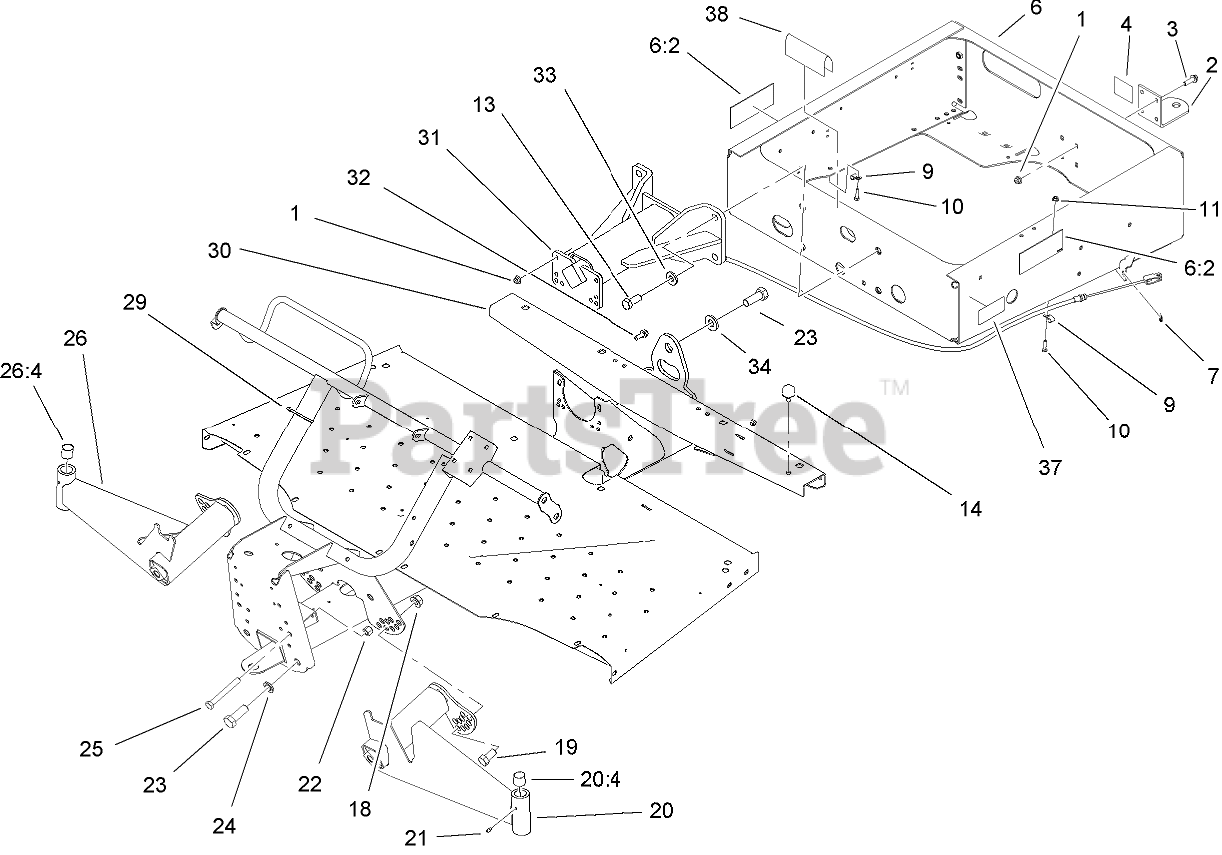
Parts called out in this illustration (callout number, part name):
1	NUT-HF, NI
2	HITCH-DUTY, LIGHT
3	SCREW-HHF
4	DECAL-RATING, HITCH (LIGHT DUTY)
6	REAR FRAME ASM
6:2	DECAL-WARNING
7	RING-RETAINING, EXTERNAL
9	CLAMP-R
10	SCREW-HH
11	NUT-HF
13	SCREW-HH
14	BUMPER-RUBBER
18	NUT-HF
19	SCREW-HH
20	LH A-ARM ASM
20:4	BUSHING
21	FITTING-GREASE
22	NUT-LOCK, NI
23	SCREW-HH
24	WASHER-LOCK, INT
25	SCREW-HH
26	RH A-ARM ASM
26:4	BUSHING
29	TIE-CABLE
30	Front Frame ASM
31	PIVOT YOKE ASM
32	SCREW-HHF
33	WASHER-FLAT
34	WASHER-HARDENED
37	DECAL-CAPACITY (CE)
